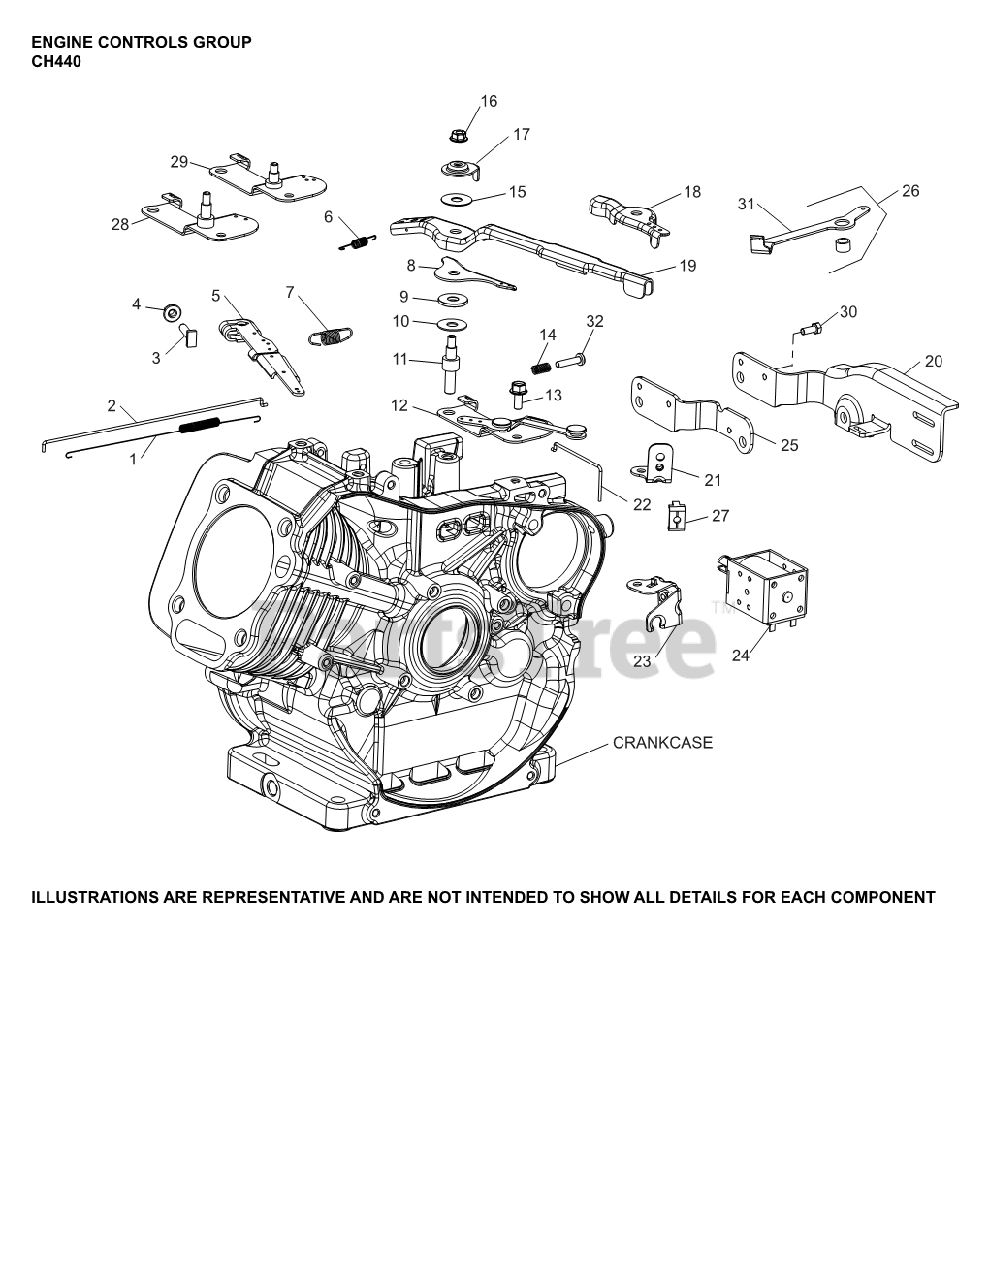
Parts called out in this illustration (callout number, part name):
1	SPRING, LINKAGE
2	LINKAGE, GOVERNOR
3	SCREW, RECTANGLE HEAD (M6)
4	NUT, HEX FLANGE (M6) - USE 14 100 16-S
5	LEVER, GOVERNOR
7	SPRING, GOVERNOR
8	LEVER, FIXED SPEED
11	STUD, CONTROL LEVER
14	SPRING, COMPRESSION
16	NUT, HEX FLANGE LOCK (M6)
24	SOLENOID, IDLE (WELDED) USE 17 435 09-S
32	SCREW, SPEED ADJUSTING (CKY)
